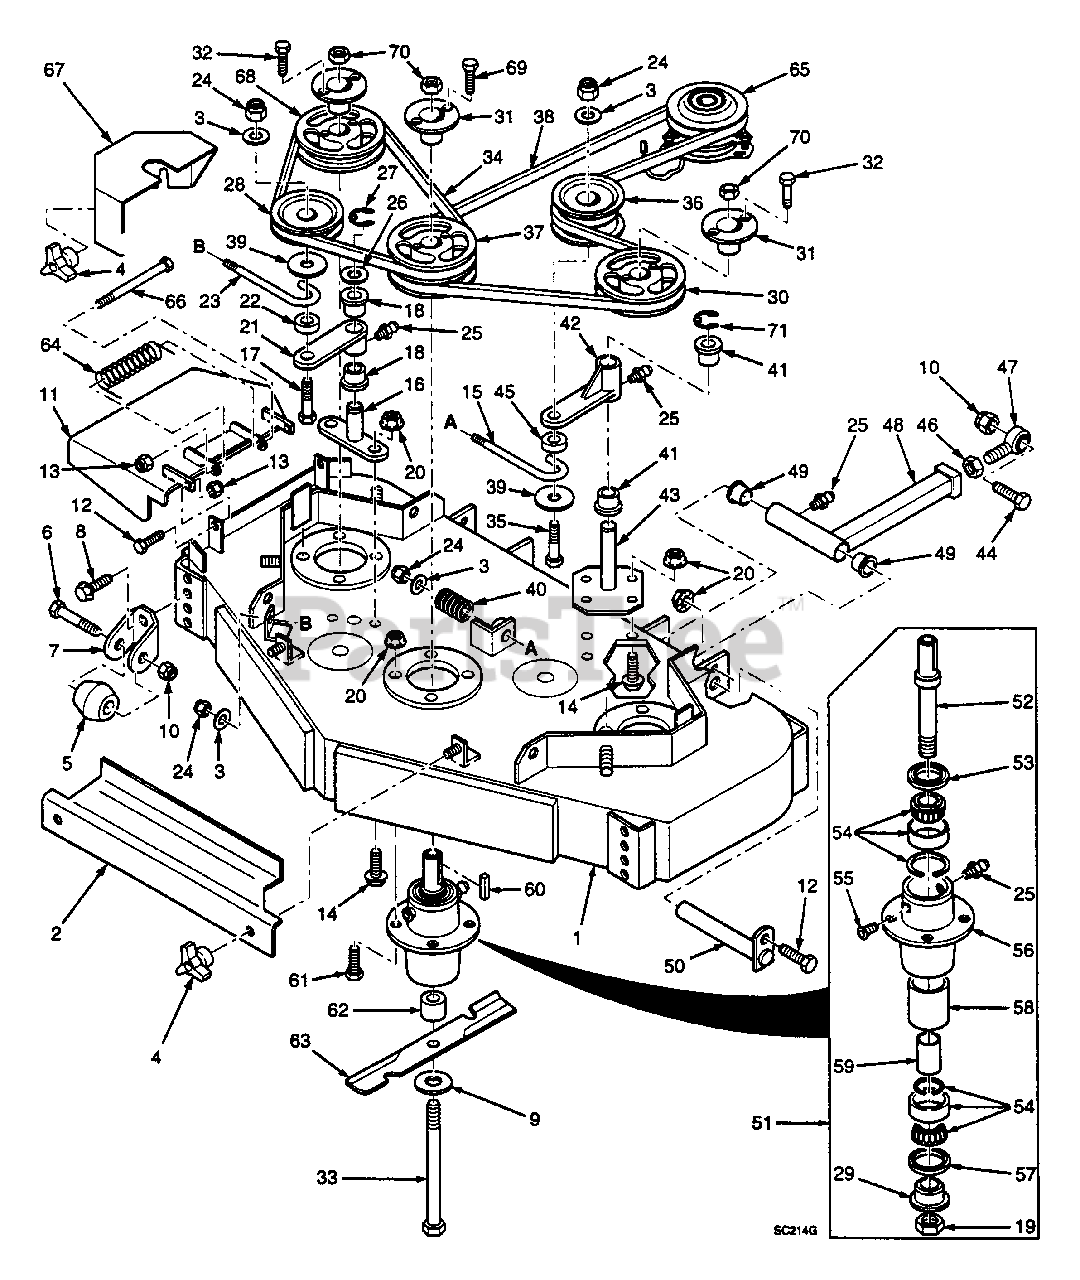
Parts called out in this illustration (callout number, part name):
1	Cutter Deck
2	Belt Cover, Front
3	Flatwasher, 3/8" Special (.391 x .938 x .105)
4	Wing Nut, 3/8-16
5	Anti-Scalp Wheel
6	Bolt, Hex Head 5/8-11 x 4-1/2
7	Anti-Scalp Wheel Bracket
8	Bolt, Hex Serrated Flange 3/8-16 x 1
9	Flatwasher, 5/8 (.688 x 1.75 x.134)
10	Nut, Hex Elastic Stop 5/8-11
11	Discharge Chute
12	Bolt, Hex Head 5/16-18 x 1"
13	Nut, Hex Elastic Stop 5/16-18
14	Bolt, Hex Serrated Flange 5/16-18 x 3/4
15	"J" Rod
16	Idler Pivot Base
17	Bolt, Hex Head 3/8-16 x 2-1/4
18	Bushing
19	Nut, Special 1-1/16-18
20	Nut, Hex Serrated Range 5/16-18
21	Idler Arm
22	Spacer
23	"J" Rod
24	Nut, Hex Elastic Stop 3/8-16
25	Grease Fitting
26	Flatwasher, 3/4"
27	Ring, Retaining 3/4" External "E"
28	Pulley, Idler
29	Spindle Bushing, Bottom
30	Pulley, LH Spindle
31	Tapered Hub, 1-1/8 Bore
32	Bolt, Hex Head 1/4-20 x 3/4"
33	Bolt, Hex Head 5/8-11 x 9-1/2"
34	Belt, RH Blade Drive
35	Bolt, Hex Head 3/8-16 x 4-1/2"
36	Pulley, Idler Cutter Engagement
37	Pulley, Double Groove
38	Belt, Blade Drive
39	Flatwasher, 3/8" (.375 x 1.5 x .06)
40	Spring, Idler Tension
41	Bushing
42	Idler Arm
43	Idler Pivot Base
44	Bolt, Hex Head 5/8-11 x 3"
45	Spacer
46	Nut, Hex 5/8-18 UNF
47	Rod End
48	Push Arm
49	Bushing
50	Push Arm Shaft
51	Spindle Assembly
52	Spindle Shaft
53	Seal, Top
54	Bearing Assembly
55	Relief Fitting, Tapered Spindle
56	Spindle Housing
57	Seal, Bottom
58	Spacer, Outside
59	Spacer, Inside
60	Key, 1/4 x 1/4 x 2"
61	Bolt, Hex Head 5/16-18 x 1-1/4"
62	Spacer, Tapered Spindle
63	Cutter Blade, 16-1/2" Standard
64	Spring, Discharge Chute
65	Electric Clutch
66	Bolt, Hex Head 5/16-18 x 4.25"
67	Belt Cover, LH
68	Pulley, RH Spindle
69	Bolt, Hex Head 1/4-20 x 1.375 Full Thread
70	Nut, Hex 5/8-11 UNC
71	Ring, Retaining 1-1/8" External "E"
